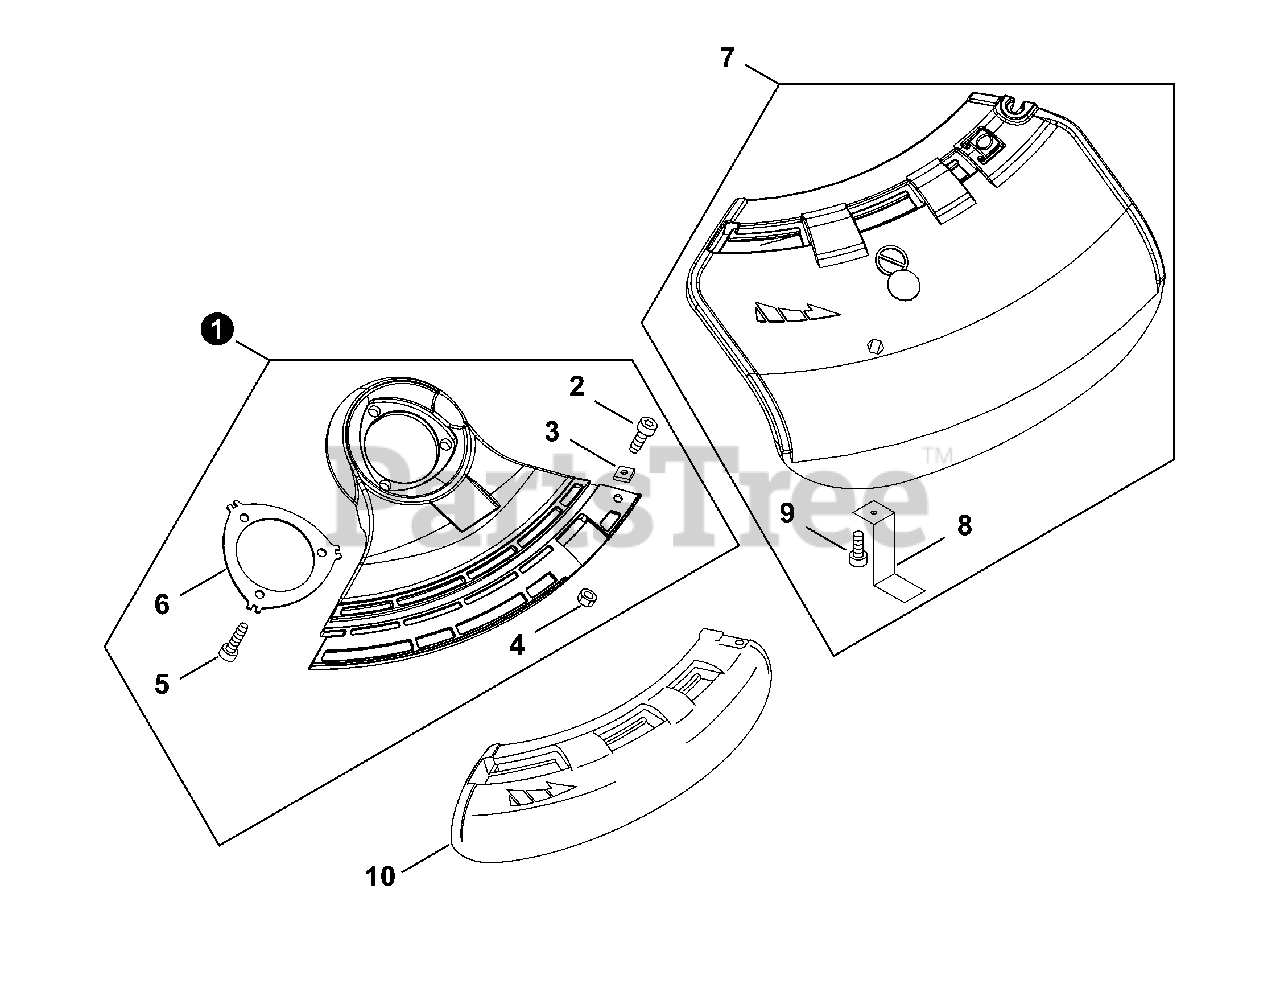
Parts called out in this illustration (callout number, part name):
1	DEBRIS SHIELD ASSY
2	BOLT, TORX 5×25
3	NUT M5
4	NUT, LOCK
5	BOLT, TORX 5×16
6	PLATE, SHIELD
7	DEBRIS SHIELD ASSY
8	CUTTER, LINE
9	BOLT, TORX 5×16
10	SHIELD, DEBRIS - BLADE EXTENSION
